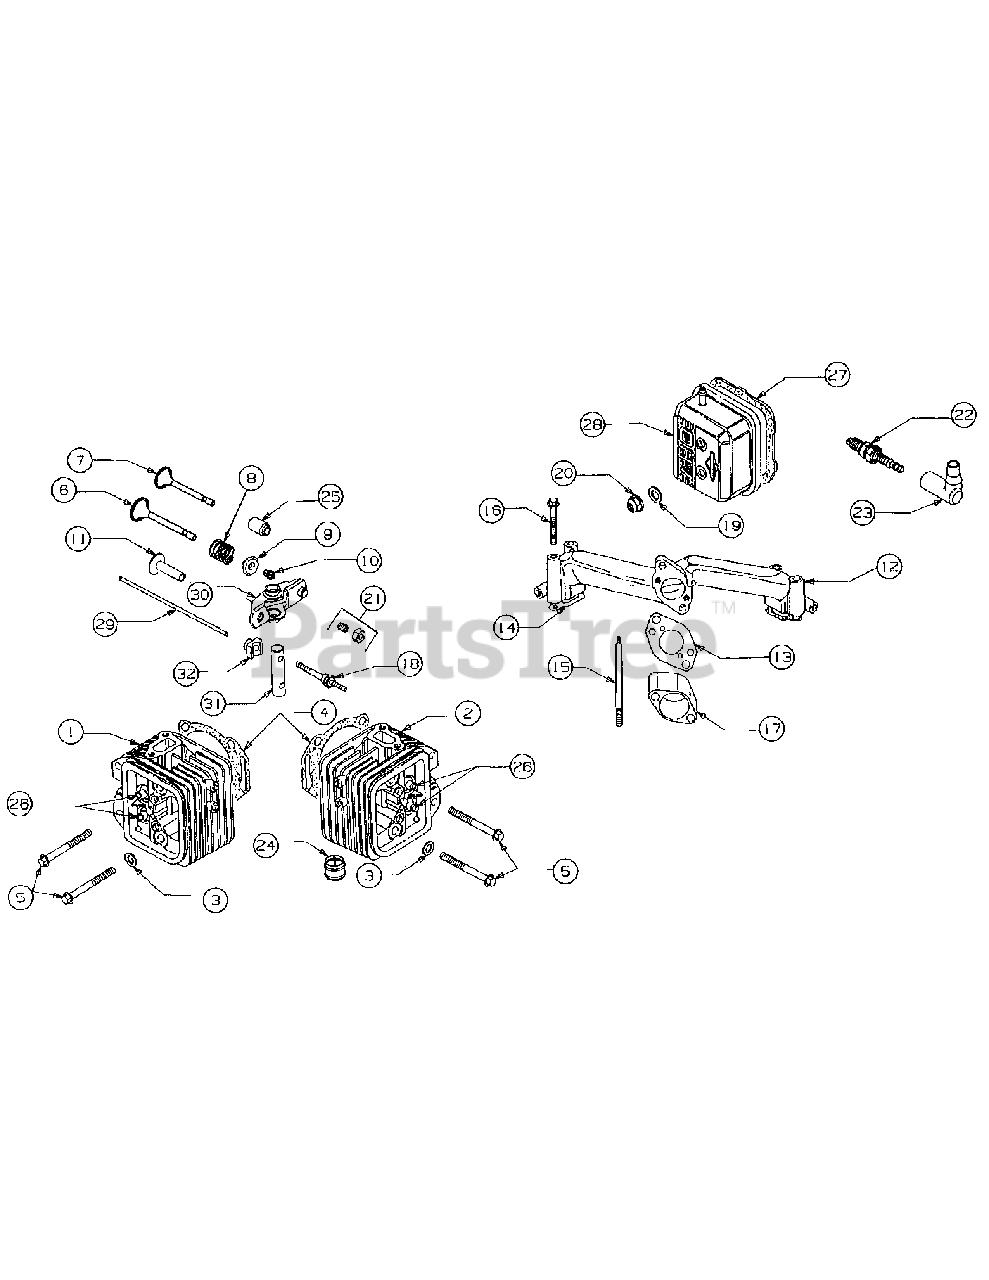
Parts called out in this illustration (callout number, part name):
1	Head, Cylinder #1
2	Head, Cylinder #2
3	Washer, Cylinder Head
4	Gasket, Cylinder Head
5	Screw, Cyliinder Head
6	Valve, Exhaust
7	Valve, Intake
8	Spring, Valve
9	Retainer, Valve Spring
10	Retainer, Valve
11	Tappet, Vavle
12	Manifold, Intake
13	Gasket, Carburetor Mtg
14	Gasket, Intake Manifold
15	Stud, Carburetor Mtd
16	Screw, Sem
17	Spacer, Carburetor
18	Stud, Rocker Arm
19	Washer, Valve Cover
20	Nut, Nylock
21	Screw, Valve Adjusting
22	Plug, Spark
23	Elbow, Spark Plug
24	Liner, Exhaust Port
25	Seal, Valve Guide
26	Guide, Valve
27	Gasket, Valve Cover
28	Cover, Valve
29	Rod, Push
30	Arm, Rocker
31	Shaft, Rocker Arm
32	Support, Rocker Arm
